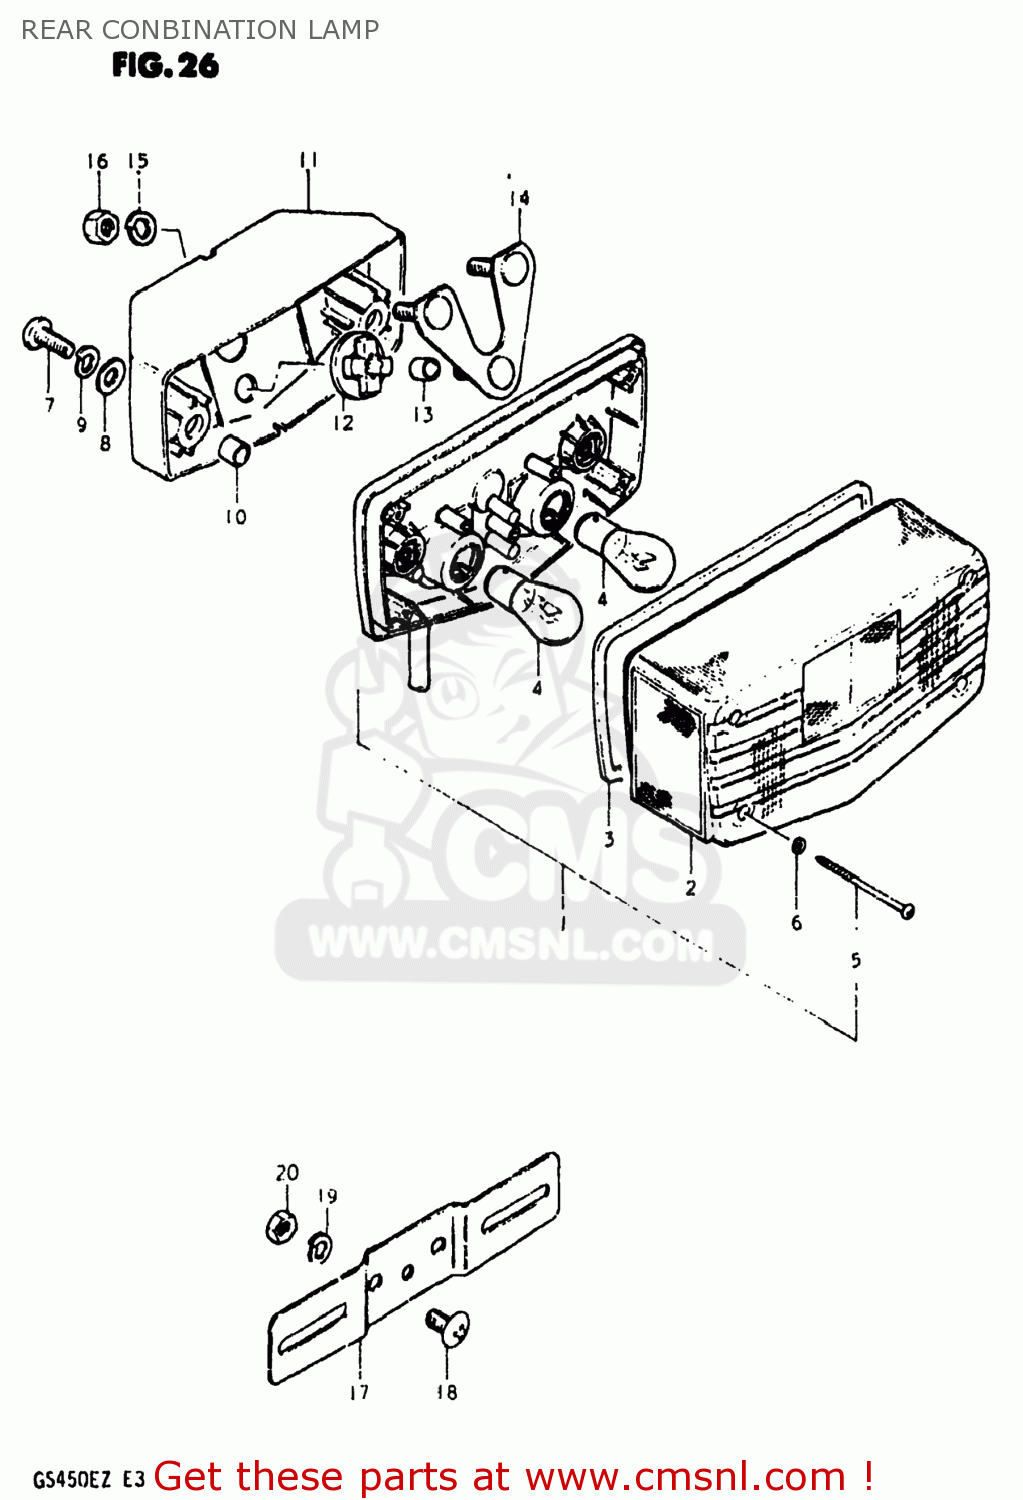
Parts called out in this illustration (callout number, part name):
1	LAMP UNIT,REAR COMBINATION
2	LENS,REAR COMBINATION LAMP
3	GASKET,REAR COMBINATION LAMP LENS (NAS)
4	BULB(12V23W)
5	SCREW
6	GASKET (NAS)
7	SCREW
8	WASHER
9	LOCK WASHER
10	SPACER,REAR COMBINATION LAMP
11	BRACKET UNIT,TAIL LAMP
12	CUSHION,REAR COMBINATION LAMP
13	SPACER,REAR COMBINATION LAMP
14	PLATE,REAR COMBINATION LAMP
15	LOCK WASHER
16	NUT
17	PLATE,REAR LICENSE
18	SCREW
19	LOCK WASHER
20	NUT
